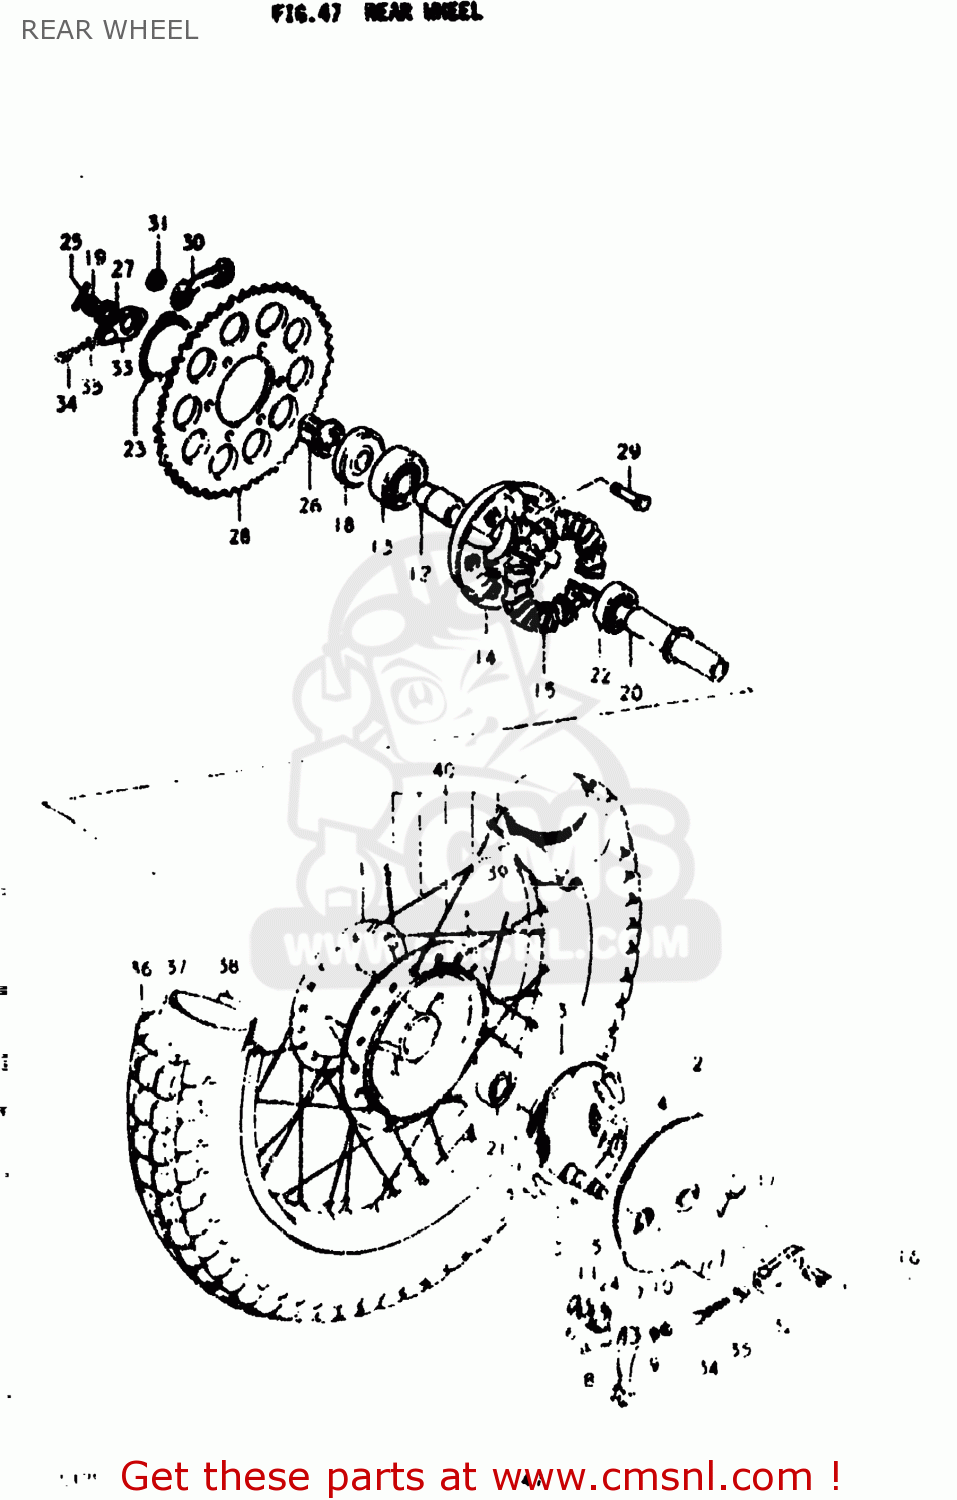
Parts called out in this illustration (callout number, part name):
1	HUB,REAR
2	PANEL,REAR HUB
3	SHOE,BRAKE
4	SPRING(L:34)
5	CAM, BRAKE
6	O RING(D:2.5,ID:11.4)
7	LEVER,REAR BRAKE CAM
8	BOLT
9	WASHER
10	NUT
11	WASHER(12.5X20X1)
12	SPACER,REAR HUB BEARING
13	BEARING
14	DRUM,REAR SPROCKET MOUNT
15	ABSORBER,RR WHEEL HUB SHOCK
16	AXLE,REAR
17	SPACER
18	SPACER,RR AXLE,L
19	NUT 12MM
20	SPACER
21	BEARING
22	BEARING
23	CIRCLIP
24	SPRING
25	COTTER PIN
26	SPACER,REAR AXLE
27	NUT
28	SPROCKET,REAR
29	BOLT(8X32)
30	WASHER
31	NUT
32	ADJUSTER,CHAIN
33	ADJUSTER,CHAIN
34	BOLT
35	NUT
36	TIRE
37	TUBE ASSEMBLY,WHEEL,INNER
38	PROTECTOR,WHEEL,INNER
39	RIM,REAR WHEEL
40	SPOKE SET,REAR
